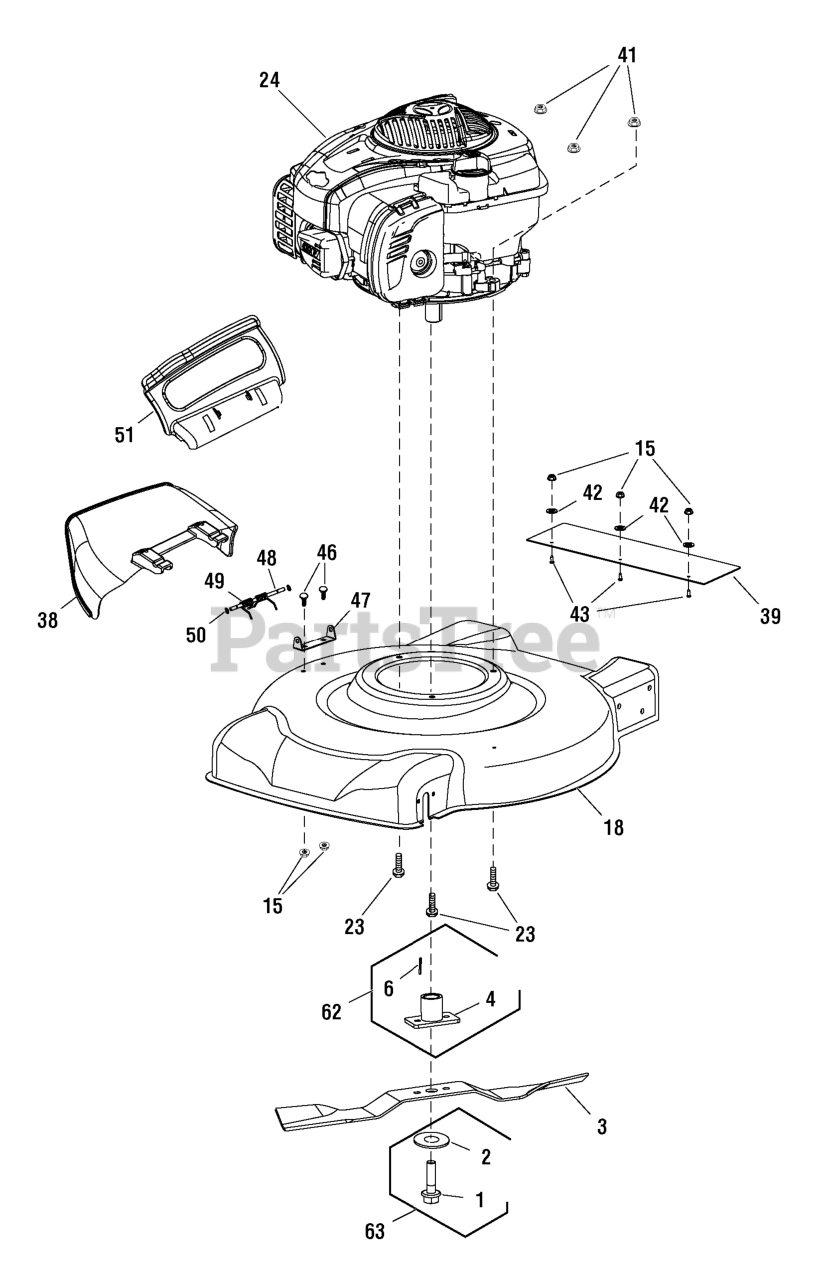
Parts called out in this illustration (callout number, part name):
1	BOLT, Blade, 3/8-24UNF
2	WASHER, Flat
4	ADAPTER, Blade
15	NUT, M6
23	BOLT, Flange, M8 x 35
38	CHUTE, Side Discharge
41	NUT, M8
42	WASHER, 6.4 x 20 x 2
43	SCREW, M6 x 16
46	BOLT, M6 x 16
47	BRACKET, Discharge Chute
49	SPRING, Discharge chute
50	CIRCLIP
51	COVER, Mulching
62	KIT, Blade Adapter
63	KIT, Hardware, Blade Bolt
